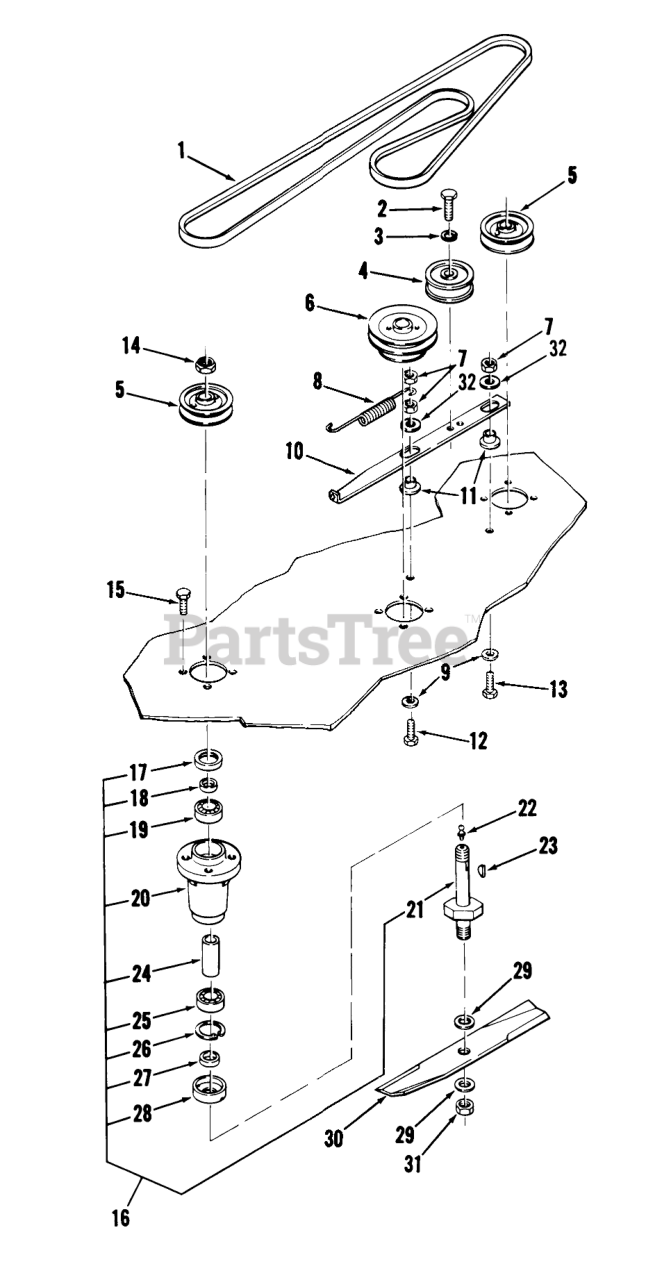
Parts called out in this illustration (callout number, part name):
1	V-BELT
1	V BELT
2	BOLT HEX SPECIAL
3	LOCKWASHER
4	Idler Pulley
5	PULLEY-BLADE DRIVE
6	PULLEY-48 MOWER SPDL
6	PULLEY-42 MOWER SPDL
7	Nut
8	SPRING-EXTENSION
9	WASHER
10	BAR-IDLER SUPPORT
11	SPACER-BUSHING
12	Bolt
13	Bolt
14	Nut
15	Bolt
16	Spindle Assembly
18	SPACER-SEAL
19	BEARING-BALL
20	HOUSING-SPINDLE
21	Spindle Shaft
22	Grease Fitting
23	Hi-Pro Key 3/16 x 5/8
24	SPACER
25	BEARING-BALL
26	Ring-Snap
27	SPACER-BLADE
28	CUP-SPINDLE
29	SpeciaI Washer
30	BLADE KIT (3 PACK)
30	14IN BLADE KIT
31	Nut
32	WASHER
